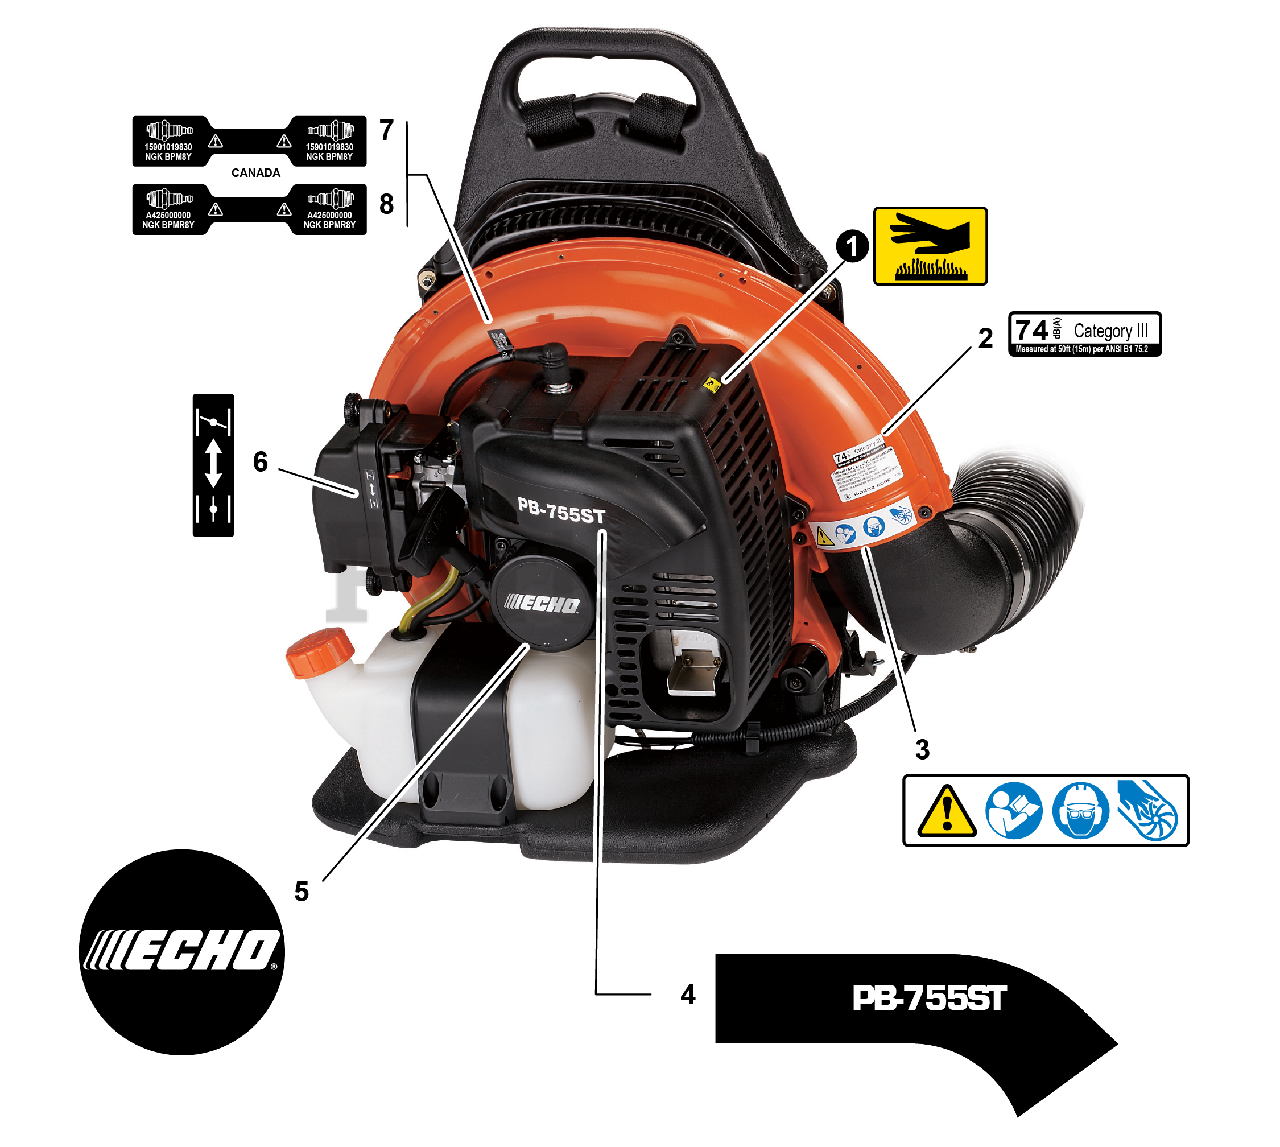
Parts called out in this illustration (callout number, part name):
1	LABEL, CAUTION - HOT
2	LABEL, NOISE
3	LABEL, CAUTION - ISO
4	LABEL, MODEL
5	LABEL, ECHO
6	LABEL, CHOKE
7	LABEL, SPARK PLUG - BPM8Y
8	LABEL, SPARK PLUG - BPMR8Y
